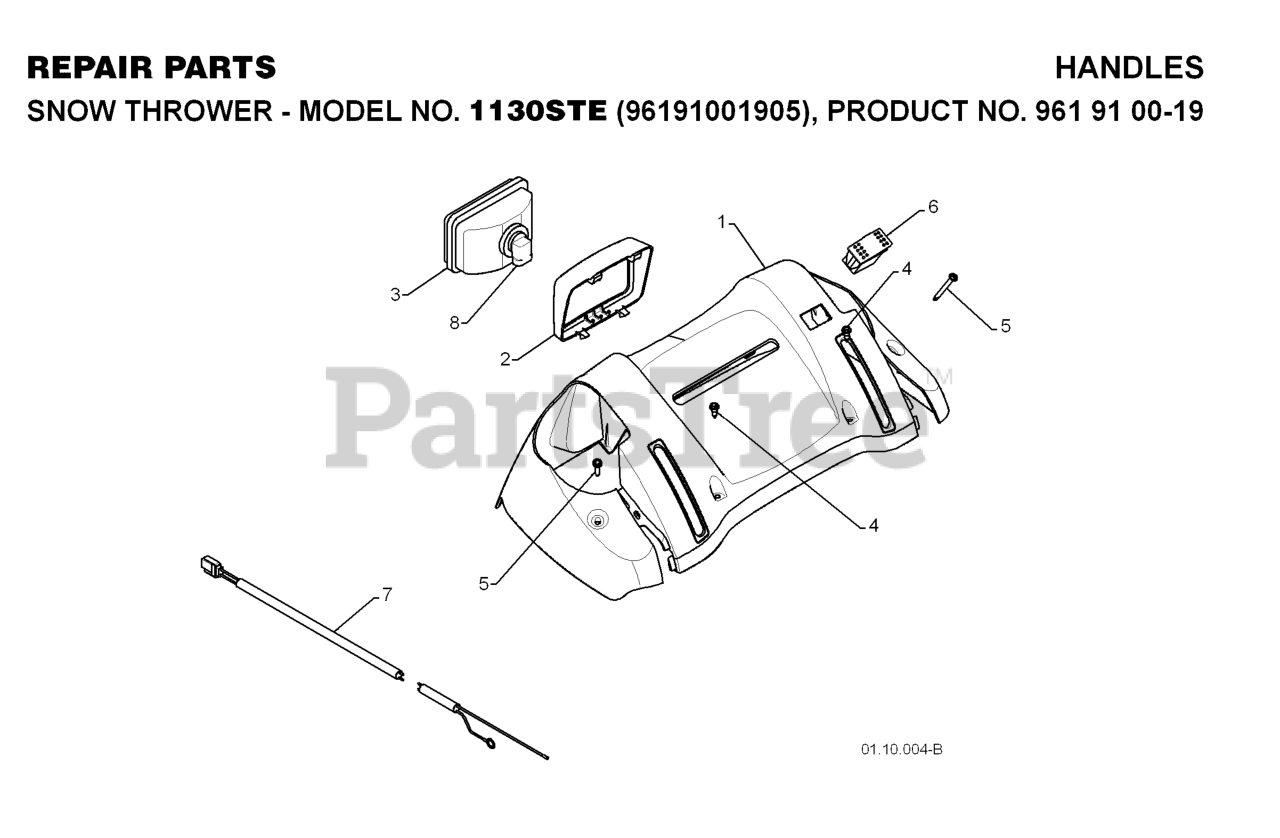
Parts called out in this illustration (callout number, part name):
1	PANEL.CONSOLE.LIGHT.REM.SWITCH
2	BEZEL.HEADLIGHT.BLACK
3	HEADLIGHT.HALOGEN.SNOW
4	SCREW, HEX HEAD, TAPPING
5	SCREW, HEX HD TAPPING #10-24 1
6	SWITCH.HEATED.GRIP
7	HARNESS.WIRE.LIGHT/GRIP.SNOW
8	BULB.HEADLIGHT.HALOGEN.
